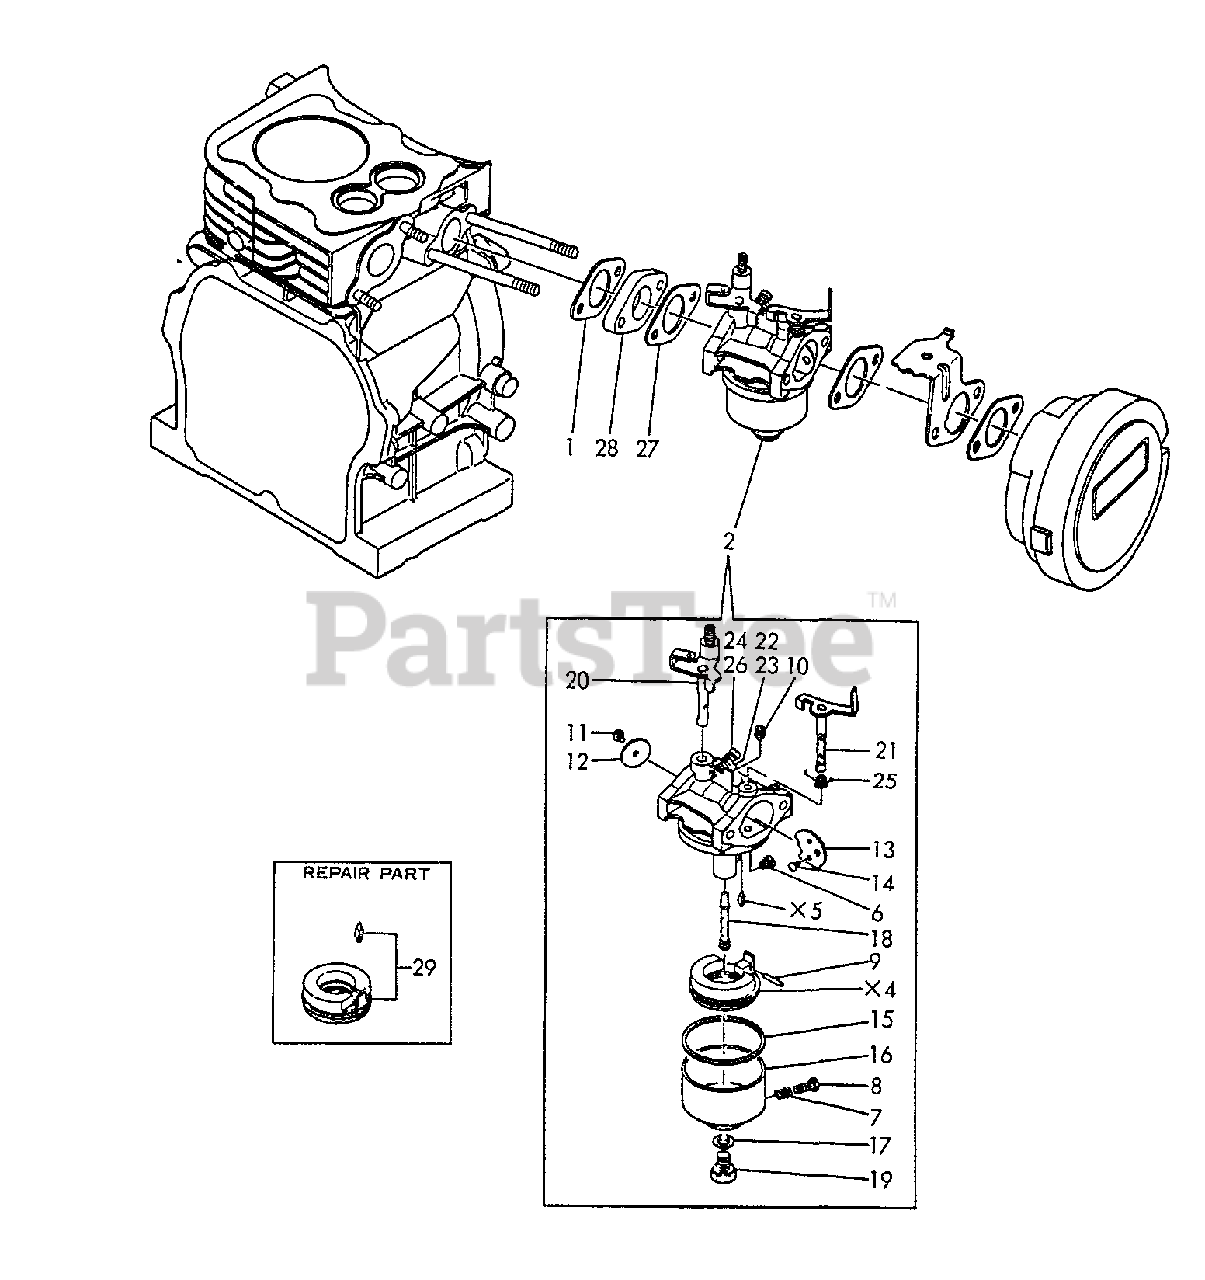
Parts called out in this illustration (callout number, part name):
1	GASKET, EXHAUST
2	CARBURETOR
4	FLOAT
5	NEEDLE
6	JET, MAIN
8	SCREW
9	PIN
10	JET, PILOT
11	SCREW
12	VALVE, THROTTLE
13	VALVE, CHOKE
15	GASKET
16	BODY, FLOAT CHAMBER
17	WASHER
18	NOZZLE
19	BOLT
20	SHAFT, THROTTLE
21	SHAFT, CHOKE
22	SCREW, THROTTLE
23	SPRING
24	SCREW, PILOT
25	SPRING
26	SPRING
27	GASKET, INTAKE
28	INSULATOR, INTAKE
29	NEEDLE ASSY - RUBBER
